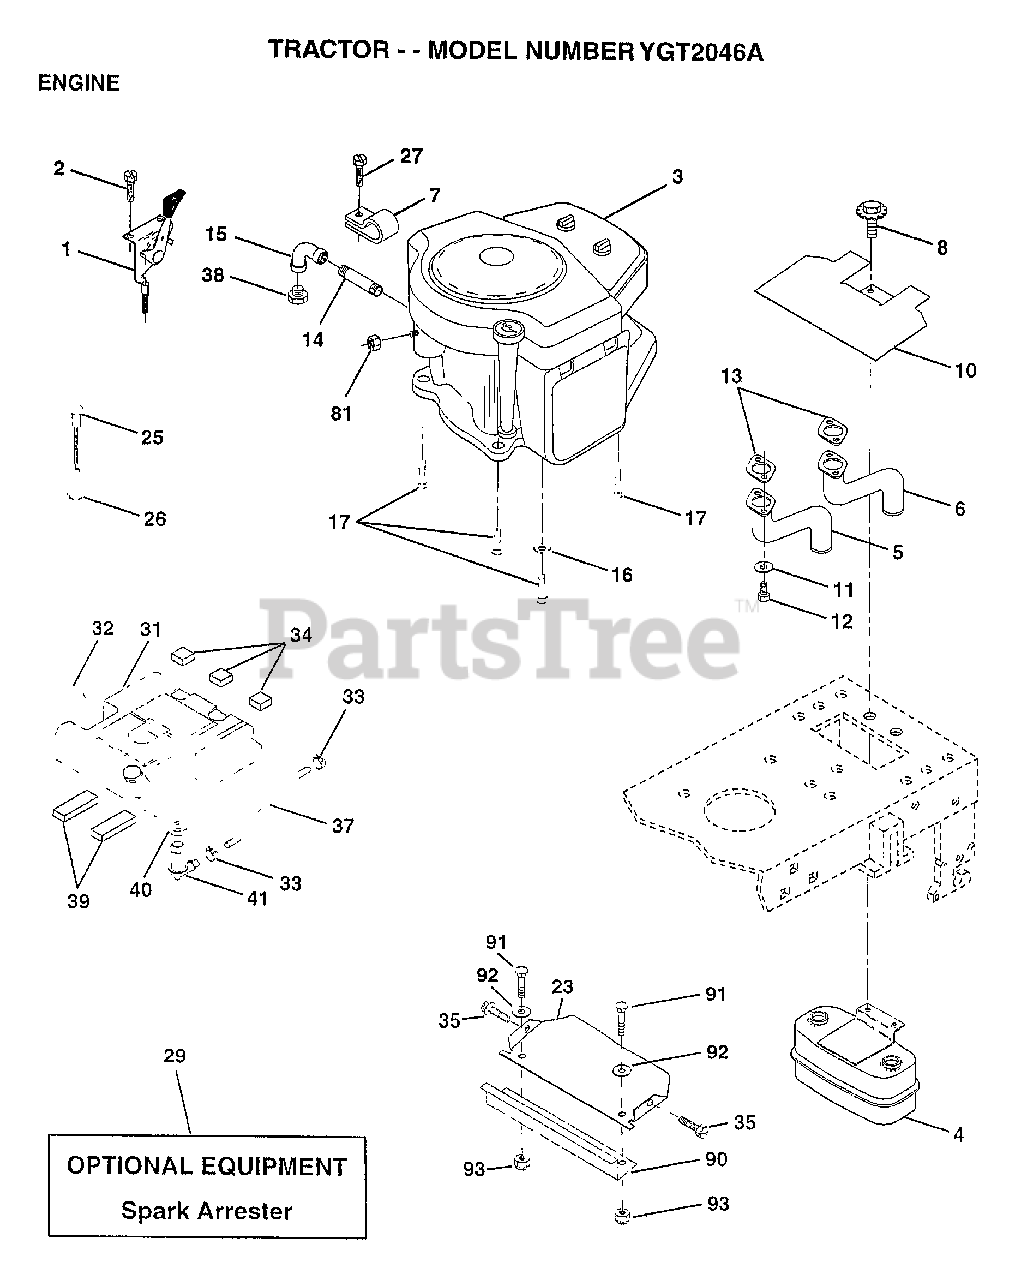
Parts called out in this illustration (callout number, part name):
2	SCREW LT
4	MUFFLER.TW.LOTONE
5	TUBE ASSY EXH LH
6	TUBE ASSY EXH RH
7	CLAMP.TUBE.DBL.EN
8	BOLT.5/16-18.UNC
10	SHIELD.HEAT.
14	PIPE NIPPLE LT
15	ELBOW
16	LOCKWASHER
17	SCREW
23	SHIELD-HEAT
25	"CONTROL.CHOKE.51"""
26	"NUT,KEPS 3/8-24IM"
27	"SCREW-TT,10-32 FL"
31	TANK FUEL REAR
32	CAP ASM FUEL
33	HOSE CLAMP
34	PAD-SPACER LT
35	SCREW
37	FUEL LINE T
39	PAD IDLER TI
40	BUSHING OUTLET T
41	STEM.TANK.FUEL
81	NUT
90	GUARD-DEBRIS
91	BOLT HXHD FIN
92	WASHER
